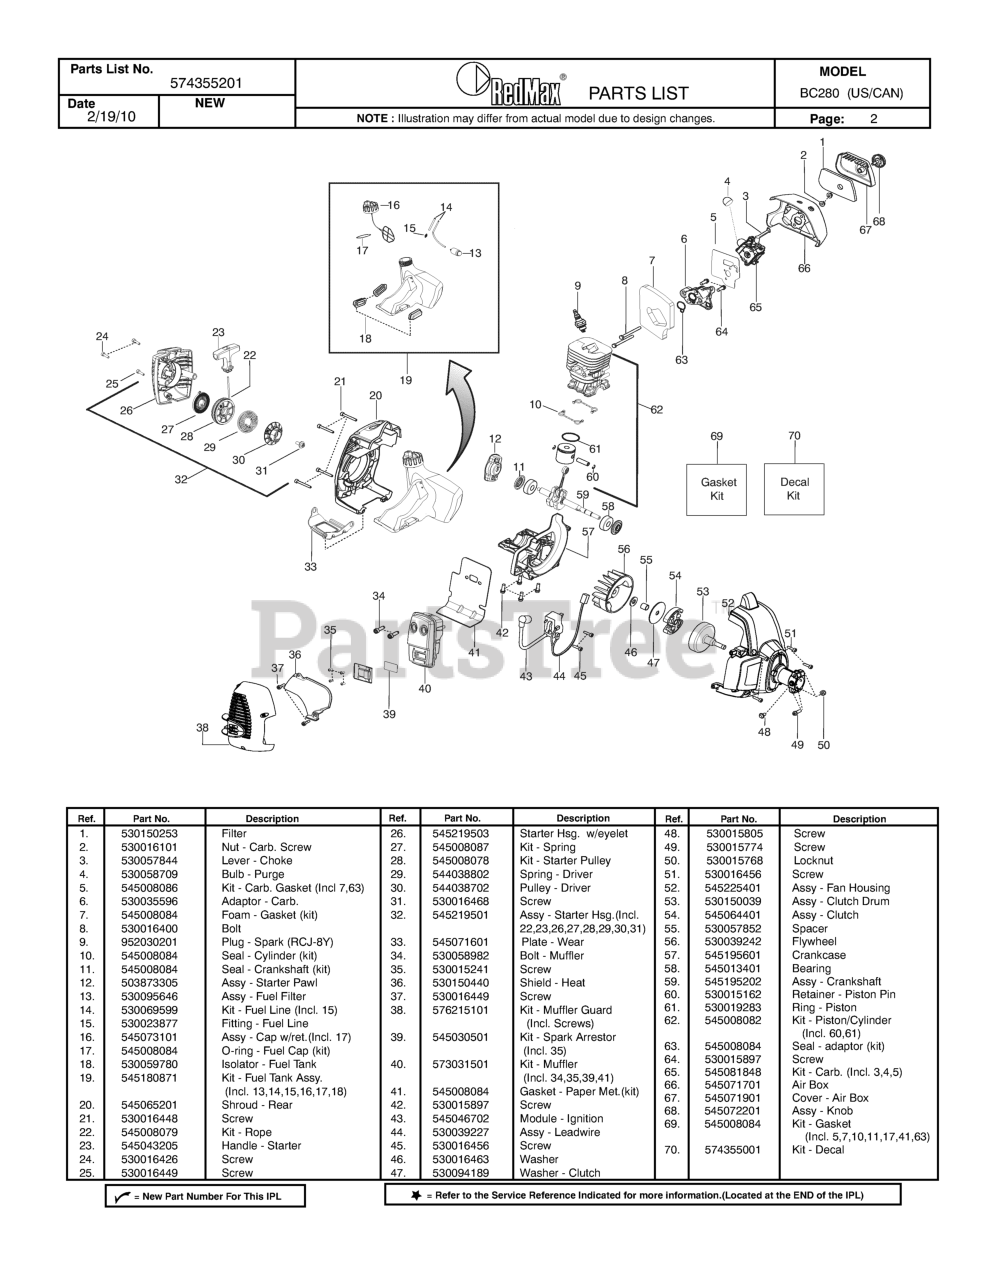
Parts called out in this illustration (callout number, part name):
2	NUT - CARB SCREW
3	LEVER CHOKE
4	BULB PURGE
5	KIT CARB GASKET
6	ADAPTER CARB
7	FOAM GASKET
9	SPARK PLUG
10	FOAM GASKET
11	FOAM GASKET
12	STARTER PAWL BRI
13	ASSY - FUEL PICKUP
14	KIT FUEL LINE
16	ASSY - FUEL CAP W/RETAINER
17	FOAM GASKET
18	ISOLATOR FUEL TANK
19	KIT FUEL TANK ASSY
20	SHROUD REAR
22	KIT ROPE
23	HANDLE - STARTER
26	STARTER HOUSING W/EYELET
27	KIT SPRING
28	KIT STARTER PULLEY
29	SPRING DRIVER
30	PULLEY DRIVER
32	ASSY STARTER HSG
33	PLATE WEAR
34	BOLT - MUFFLER
36	HEAT SHIELD
38	KIT MUFFLER GUARD
39	KIT SPARK ARRESTOR
40	KIT MUFFLER
41	FOAM GASKET
43	IGNITION MODULE
44	LEADWIRE ASSY
47	WASHER CLUTCH
48	SCREW
52	FAN HOUSING ASSY
53	CLUTCH DRUM ASSY
54	CLUTCH ASSY
56	FLYWHEEL
57	CRANKCASE
59	CRANKSHAFT ASSY
60	RETAINER - PISTON PIN
61	RING - PISTON
62	KIT PISTON/CYLINDER
63	FOAM GASKET
65	KIT CARB
67	COVER AIR BOX
68	ASSY - AIR BOX KNOB
69	FOAM GASKET
70	KIT-DECAL
